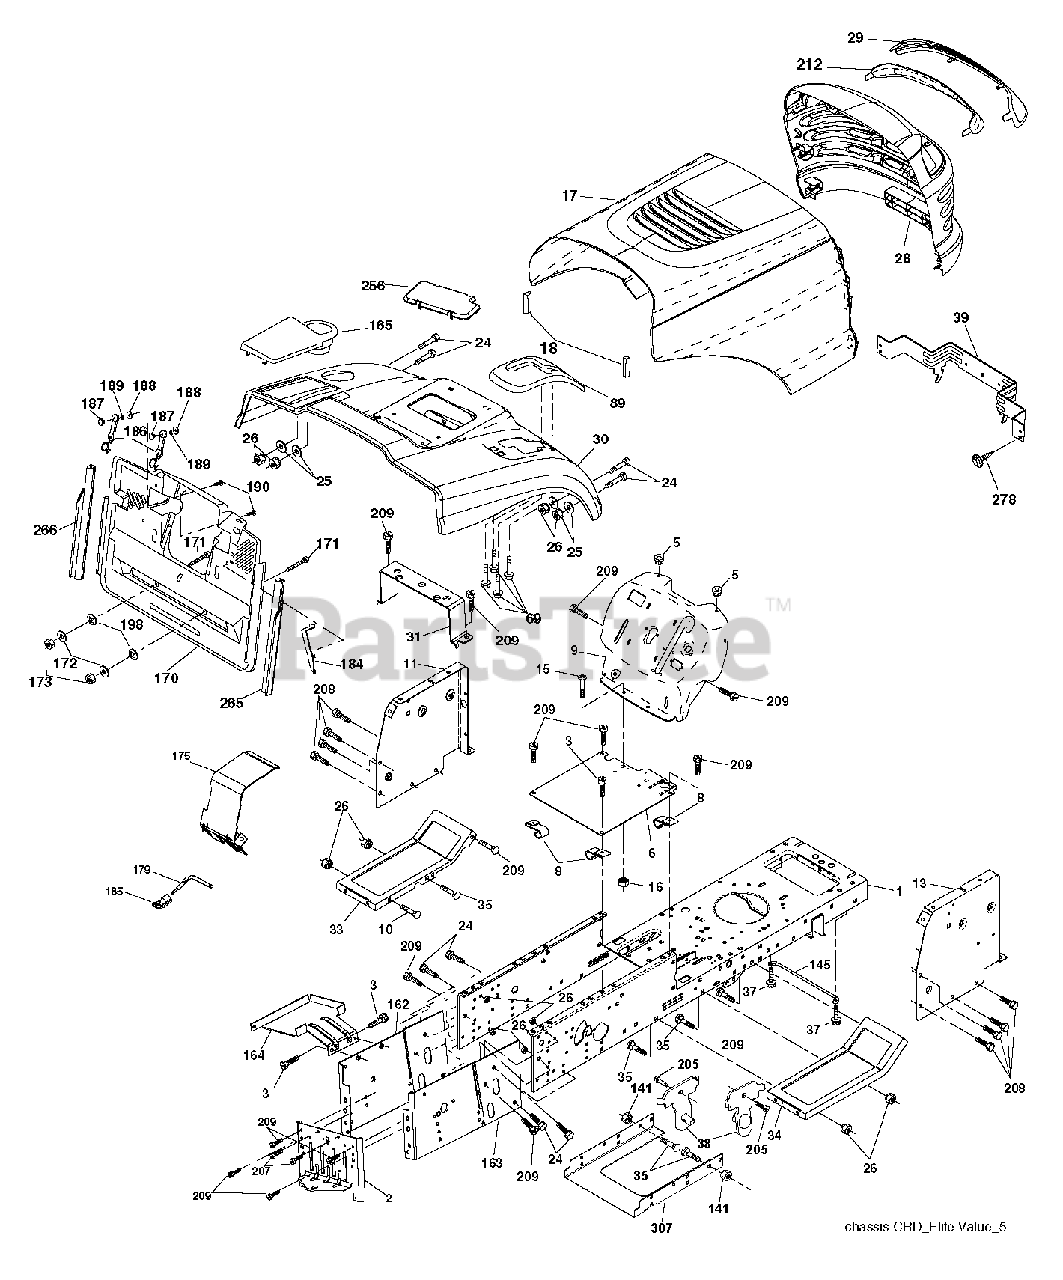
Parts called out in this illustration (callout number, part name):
1	CHASSIS
3	SCREW 3/8-16X3/4
5	BUMPER.RUBBER.HOOD
8	CLIP,INSULATOR
10	BOLT D
11	PANEL.DASH.LH.LTX
13	PANEL DASH RH
16	NUT
17	HOOD.PNT.STL.ELITE.TOPLVRS.667
18	BUMPER.HOOD.LARGE.1.75"
25	WASHER
26	NUT
28	HOOD.PNT.STL.ELITE
29	LENS GRILL VALUE BAR LT CLEAR
30	FENDER.PNT.CRD.MS667
31	BRACKET SUPPORT FENDER
33	FOOTREST.PNT.LH.MS667
34	FOOTREST.PNT.RH.MS667
39	BRACKET PIVOT
69	SCREW.HI-LO.CONSOLE
141	NUT LOCK FLG 3/8-16 UNC
145	ROD.PIVOT.HOOD
164	SUPPORT
165	FENDER.PNT.CRD.
171	BOLT
172	WASHER
184	BRACKET.ACTUATOR.BAGGER.SRD
185	KNOB.BRAKE.PARKING.ROD
187	WELDNUT
207	SCREW, 5/16-18 X 1/2
208	SCREW 3/8-16X1/2
209	SCREW, 3/8-16X3/4
256	FENDER.PNT.CRD
278	SCREW.#10 X 0.750.BOS THREAD
307	GUARD 107 CRD FRENCH
